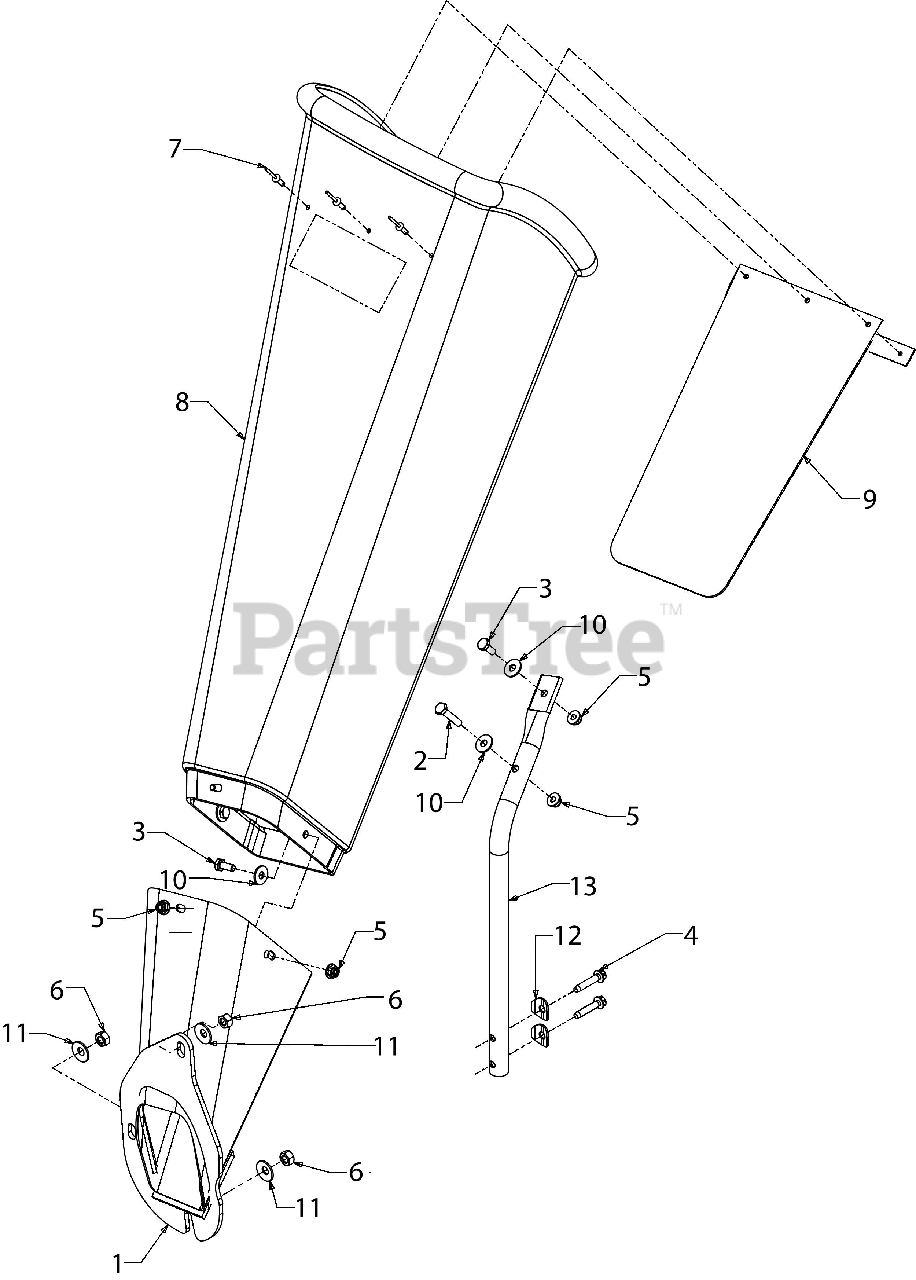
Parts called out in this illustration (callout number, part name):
1	LOWER CHIPPER CHUTE
2	HEX SCREW 1/4-20 x 1.25
3	SCREW 1/4-20 x .620 GR5
4	SCREW 1/4-20 x 1.25
5	FLANGE LOCK NUT
6	HEX NUT
7	RIVOT
8	CHIPPER SHREDDER KIT
9	CHUTE FLAP
10	FLAT WASHER .28 ID x .74 OD x .063
11	BELL WASHER .337 X.867 x .057
12	SADDLE WASHER
13	CHUTE SUPPORT
14	FLAP STRIP
